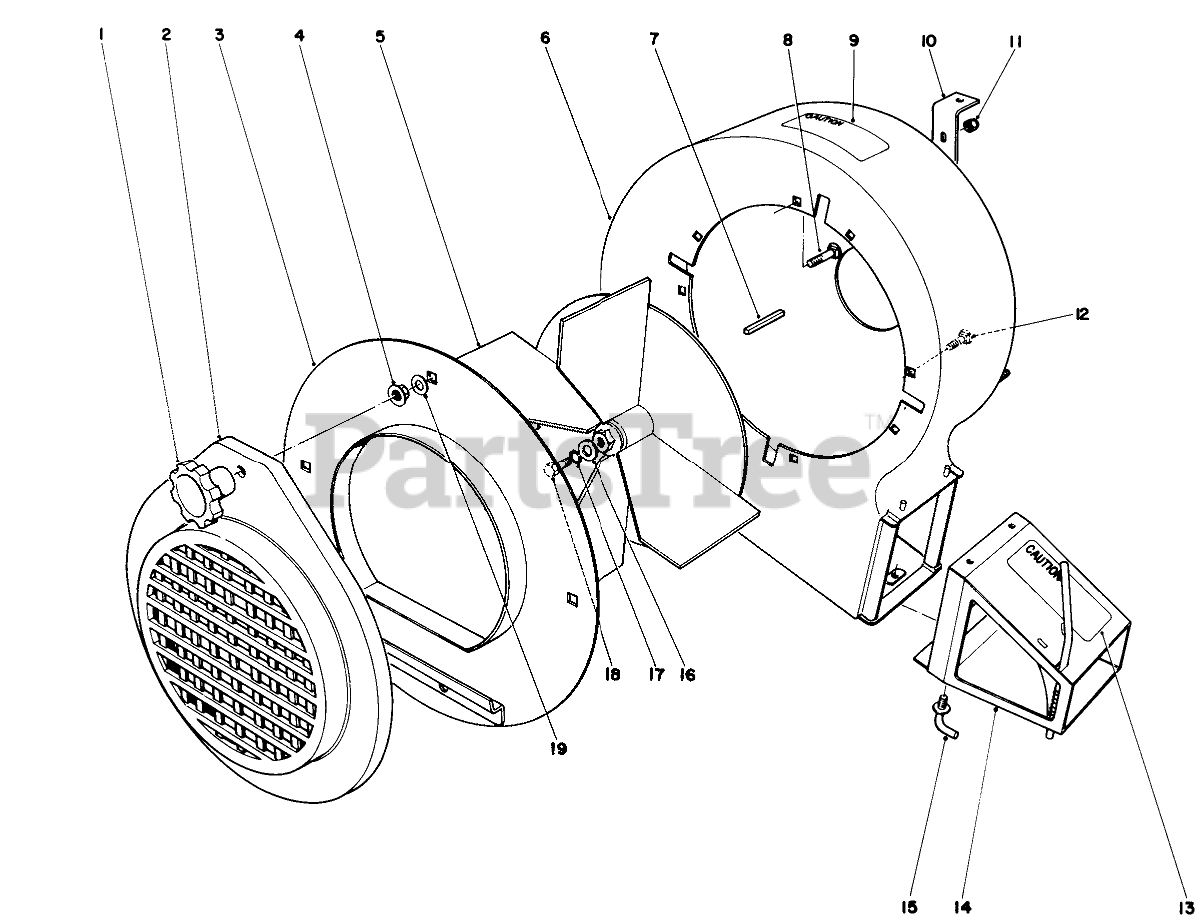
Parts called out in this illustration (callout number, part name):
2	INTAKE-BLOWER
3	Blower Cover
4	NUT-HF
5	Fan
6	Blower Housing
7	KEY-SQUARE
8	SCREW-CARR
9	Decal, Caution
10	Mounting Bracket
11	NUT-LOCK, CONE
12	SCREW-CARR
13	EXHAUST DECAL
14	EXHAUST BLOWR WA/DECAL
15	1/4 - 20 3/4 WING SCR
16	WASHER-FLAT
17	WASHER-LOCK
18	Capscrew
19	WASHER-FLAT
